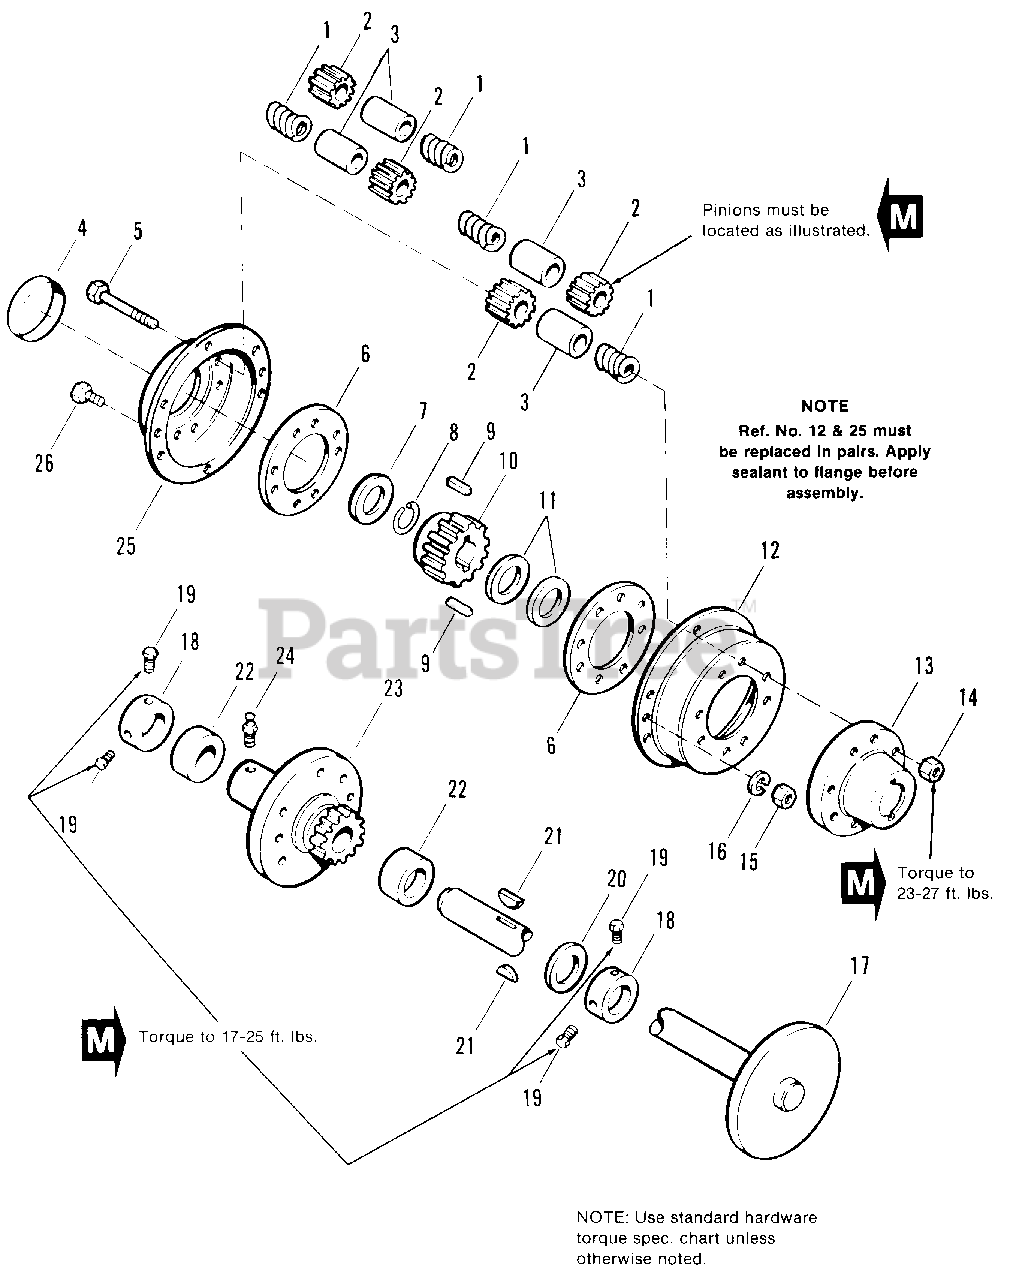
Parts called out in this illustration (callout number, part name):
1	SPRING
2	PINION, Differential
3	SPINDLE, Differential
4	SEAL, Cover
5	CAPSCREW, Hex Hd., 3/8-16 x 2-1/2
6	RING, Spacer
8	RING, Retaining
10	GEAR, Differential
12	COVER, Differential
13	CARRIER, Differential
14	LOCKNUT, Hex, 3/8-16
15	NUT, Hex, Full, 1/4-20
16	LOCKWASHER, 1/4
17	AXLE ASSY., Rear
18	COLLAR, Set
19	SETSCREW, 5/16-18 x 1/2
21	KEY, Hi-Pro
23	HUB ASSY., Wheel, RH
24	FITTING, Grease
25	COVER, Differential
26	CAPSCREW, Hex Hd., 1/4-20 x 5/8
26	DIFFERENTIAL SUBASSY. (See Note Below)
